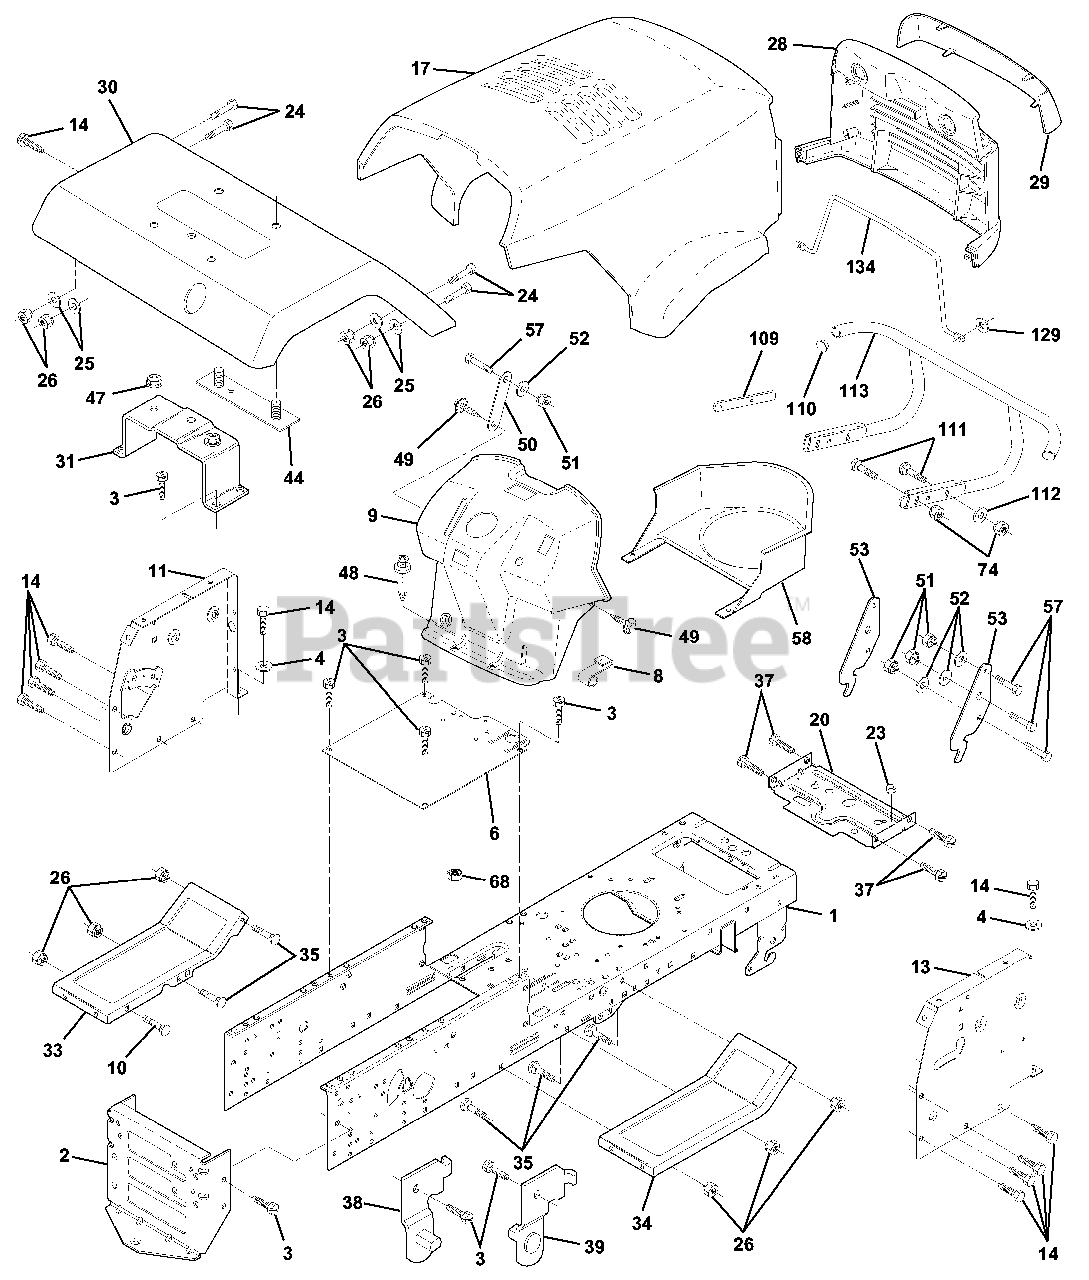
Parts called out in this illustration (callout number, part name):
1	Chassis Weldment 11ga
2	Drawbar, Stretch
3	Screw Thdrol 3/8-16x3/4 Ty-tt
4	Washer 13/32 x 3/4 x 16 Ga.
6	Saddle LT Fender Shift
8	Clip Insulator .406 Mtg Hole
9	Dash P/L N/Amm. W/HM w/PTO Grey
10	Bolt Carriage 3/8-16 x 1
11	Panel Pnt Dash Lh
13	Panel Dash Rh
14	Screw Thdrol 3/8-16x1/2 Ty-tt
17	Hood LT/PL Husqvarna
20	Plate Mtg. Battery Fuel Tank. 95
24	Bolt Fin Hex 3/8-16unc X 1 Gr. 5
25	Washer 13/32 X 13/16 X 12 Ga
26	Nut Lock Hex W/Ins 3/8-16 Unc
28	Grille LT/PL Husqvrna
29	Lens LT/PL Husqvrna
30	Fender Pnt
31	Bracket Pnt Fender
33	Footrest Pnt Lh
34	Footrest Pnt Rh
35	Bolt Rdhd Sht Sqnk 3/8-16 X3/4
37	Screw Thdrol 5/16-18 X1/2
38	Bracket, Asm. Pivot, L.H., Mower Rear
39	Bracket, Asm. Pivot, R.H., Mower Rear
44	Strap Asm., Fender 94
47	Nut, Push Nylon
48	Rivet Push Plate D Plastick Blk
49	Screw, Hexwsh. Thdrol 1/4-20 x 3/4
51	Nut Lock Hex W/Ins 1/4-20
52	Washer 9/32 x 7/8 x 16 Ga.
53	Bracket Pnt. Pick off LT/PL Husq.
57	Bolt Hex 1/4-20 x 3/4
58	Air Duct P/L
68	Nut Keps Hex 1/4-20
74	Nut Crownlock 3/8-16 UNC
109	Bracket Extension Bumper
110	Plug Plastic
111	Bolt Carriage 3/8-16 x 1-1/4
112	Washer 13/32 x 13/16 x 16 Ga.
113	Bumper Asm. 129 819091016
134	Rod Support Hood LT/PL Husq.
